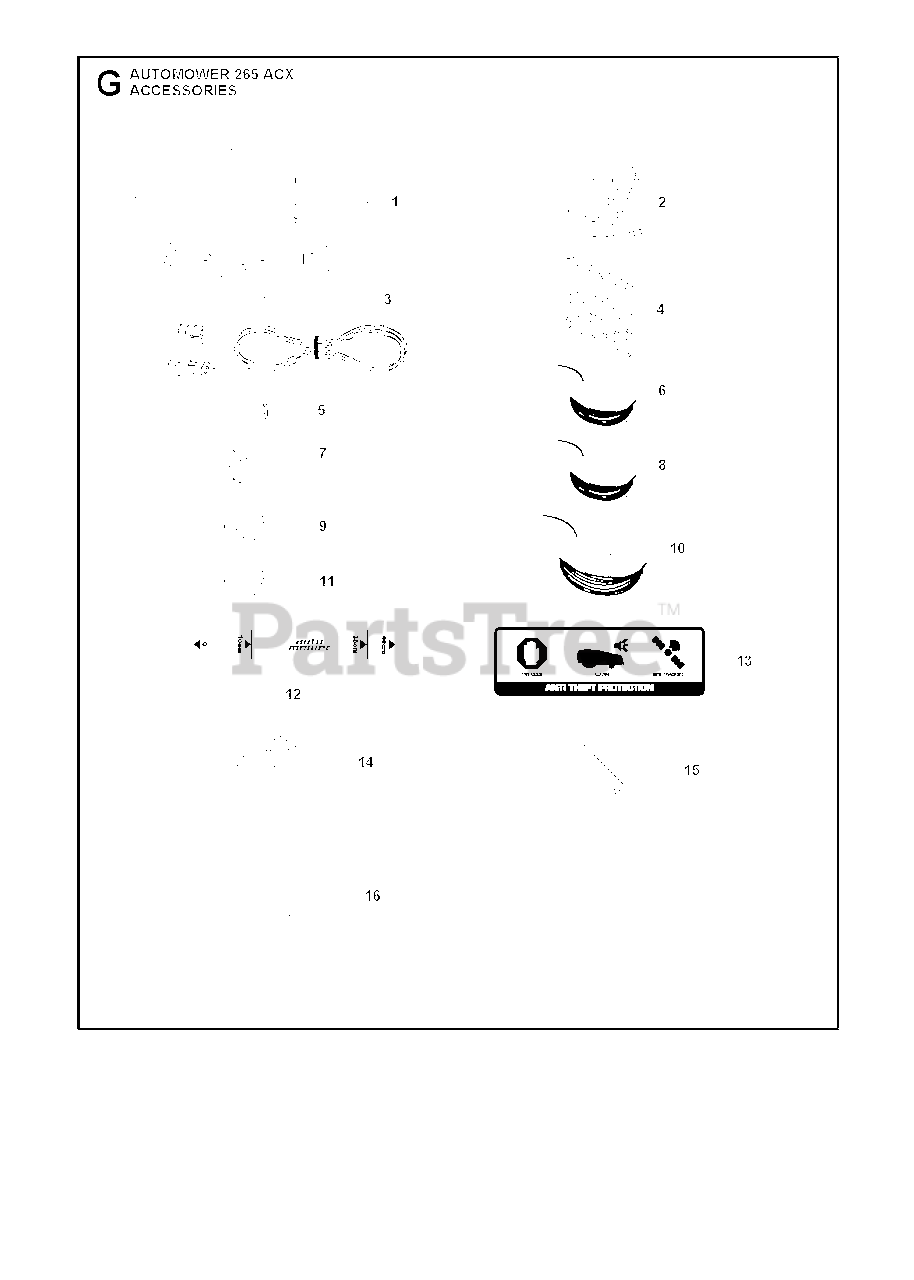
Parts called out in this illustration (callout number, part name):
2	STAPLE 100 PCS BLISTE
2	STAPLES (100 CT BAG)
4	SCREW KIT CS
4	SCREW 3 PCS, BLISTER PACK
6	LOOP WIRE 150M
6	WIRE 150M BLISTER
7	Connector, 5 Pcs Blist
7	BRAKER
8	LOOP WIRE 250M
9	Splicer Coupler, 5 Pcs
9	SPLICE KIT
10	Wire, 500M
11	SPLICE CONNECTOR 50 PCS/PK
14	PRINTED CIRCUIT ASSY
15	BRUSH KIT
